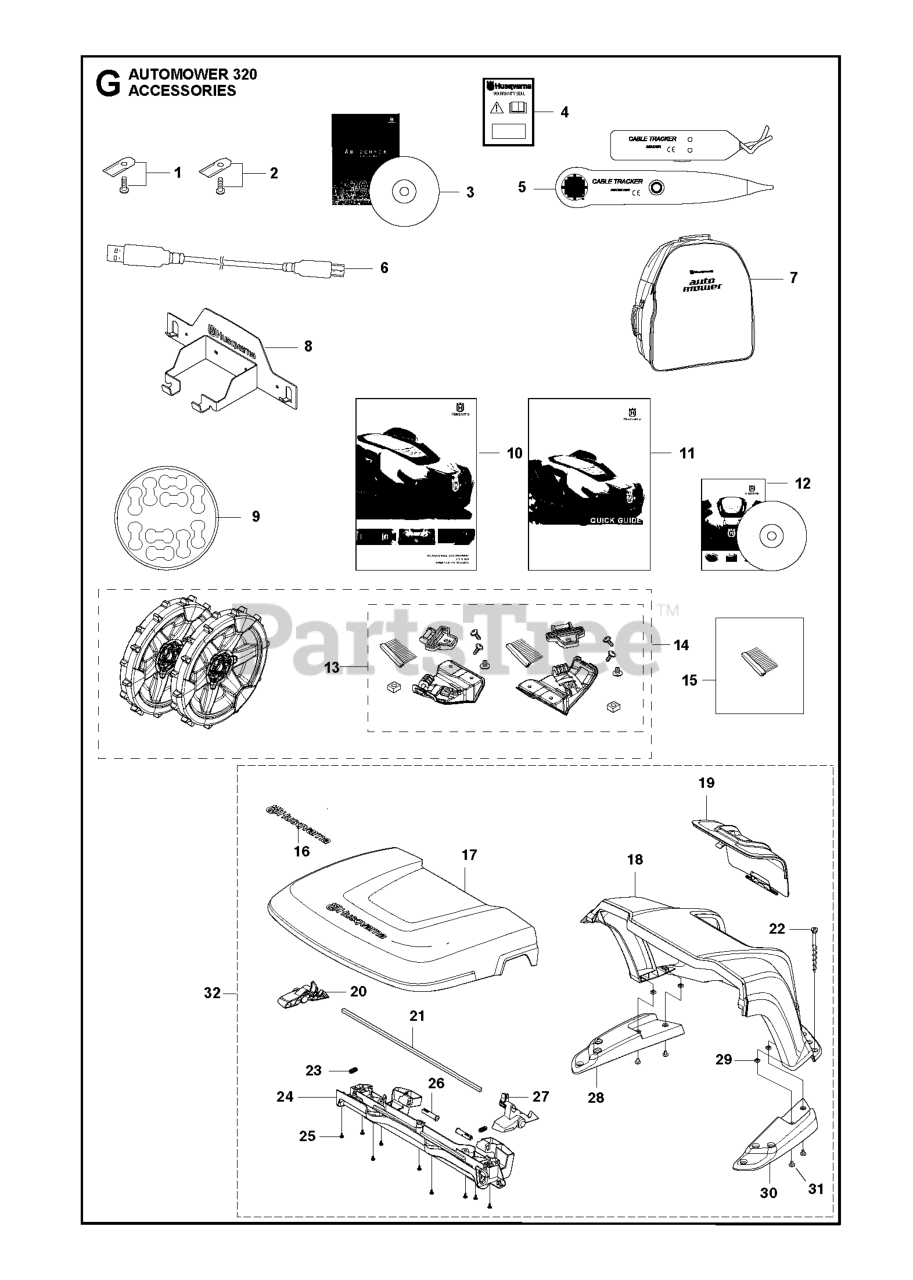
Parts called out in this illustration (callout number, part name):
1	BLADE - 30 PCS
1	BLADE KIT
1	BLADE
1	BLADE - BULK PACK 500 PCS
2	BLADE 300PCS -SINGLE HOLE THIC
2	BLADE 9PCS EXTRA THICK
2	BLADE BLADE KIT INCL PACKAGING
2	BLADE CARBON STEEL, THICK BLAD
4	LABEL WARRANTY SEAL KIT 10 PK
4	LABEL WARRANTY SEAL DEALER
5	TEST EQUIPMENT
9	STICKER CABLE MARKERS KIT 10PC
16	DECAL.HUSQVARNA.210MM
17	KIT LID - AUTOMOWER HOUSE
18	COVER BASE P2 HOUSE
20	HANDLE RELEASE LEFT
22	SCREW KIT CS
23	SPRING SPRING CAP
25	SCREW 14MM
27	HANDLE RELEASE RIGHT
28	SUPPORT BASE LEFT
30	SUPPORT BASE RIGHT
31	SCREW IHPANM M6X25 4.6 ZP-BC
32	430/450 HOUSE KIT
